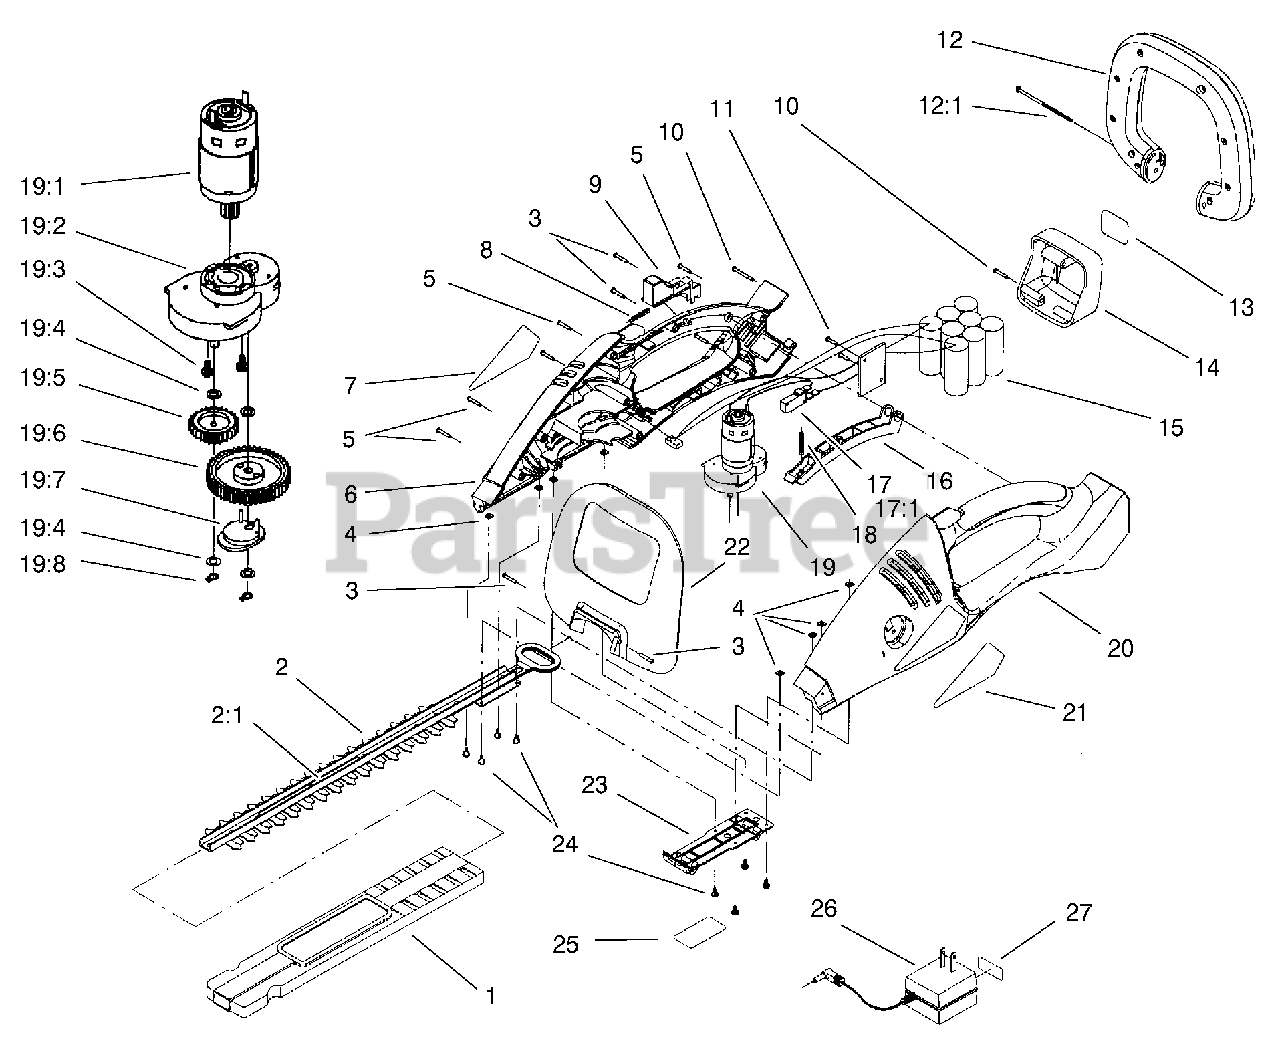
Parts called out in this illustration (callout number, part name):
1	PROTECTOR - BLADE, 16"
2	BLADE ASM
2:1	DECAL - SAFETY, BLADE
3	Screw-PPH
4	NUT - SQUARE
5	SCREW - PPH
6	Housing-Cover
7	Decal-Housing, Cover
8	SPRING - BUTTON, SAFETY
9	BUTTON - SAFETY
10	SCREW - PPH
11	Screw-PPH
12	SAFETY HANDLE ASM
12:1	SCREW - PPH
13	DECAL - COVER, BATTERY
14	COVER - BATTERY
15	BATTERY ASM
16	Button-On/Off
17	HARNESS - WIRE ASM
17:1	Switch-On/Off
18	SPRING - BUTTON, ON/OFF
19	MOTOR AND GEAR TRAIN ASM
19:1	MOTOR ASM
19:2	HOUSING - GEAR ASM
19:3	SCREW - PPH
19:4	WASHER - FLAT
19:5	Gear-Center
19:6	GEAR - FINAL
19:8	RING - RETAINING, EXTERNAL
20	Housing-Support
21	Decal-Housing, Support
22	GUARD - HAND
23	COVER - BOTTOM
24	SCREW - PPH
25	Decal-Model/Warning
27	Decal-Warning
